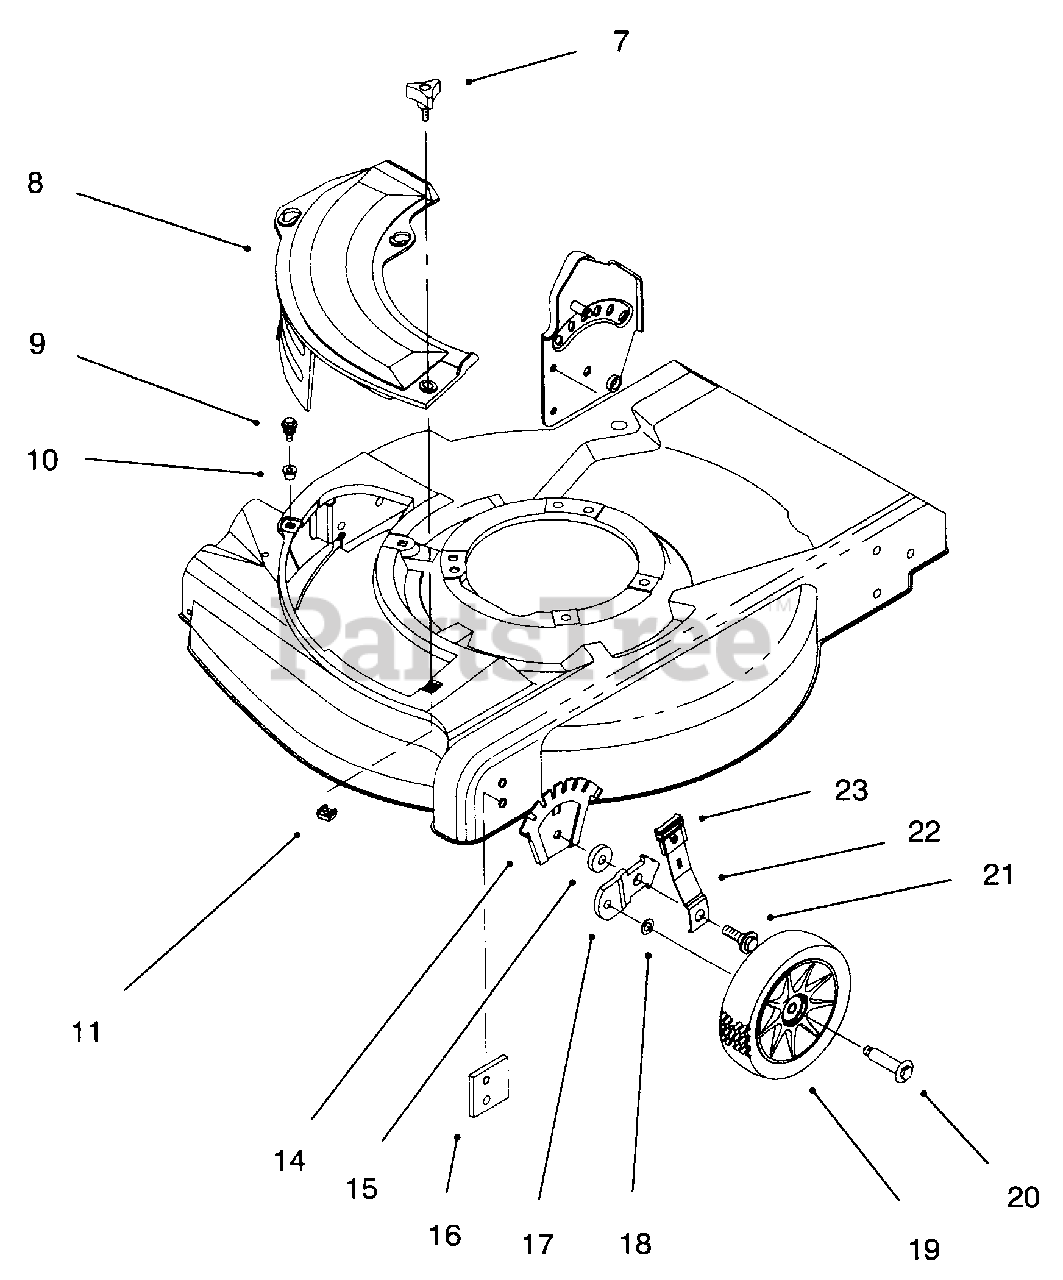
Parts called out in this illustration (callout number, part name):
7	Knob-Cover Plate
8	Plate-Mulch 21"
9	Screw-Sem Thr'd Form
10	Grommet-Plastic
11	Nut-Cage
14	Plate-Height Adjust
16	Plate-Baffle
17	Bracket-Wheel Height Adj.
19	Wheel & Tire Ass'y 6"
20	Bolt-Shoulder
21	Bolt-Shoulder Height Adj.
22	Spring Arm Ass'y-Front
23	Knob-Height Adjust
